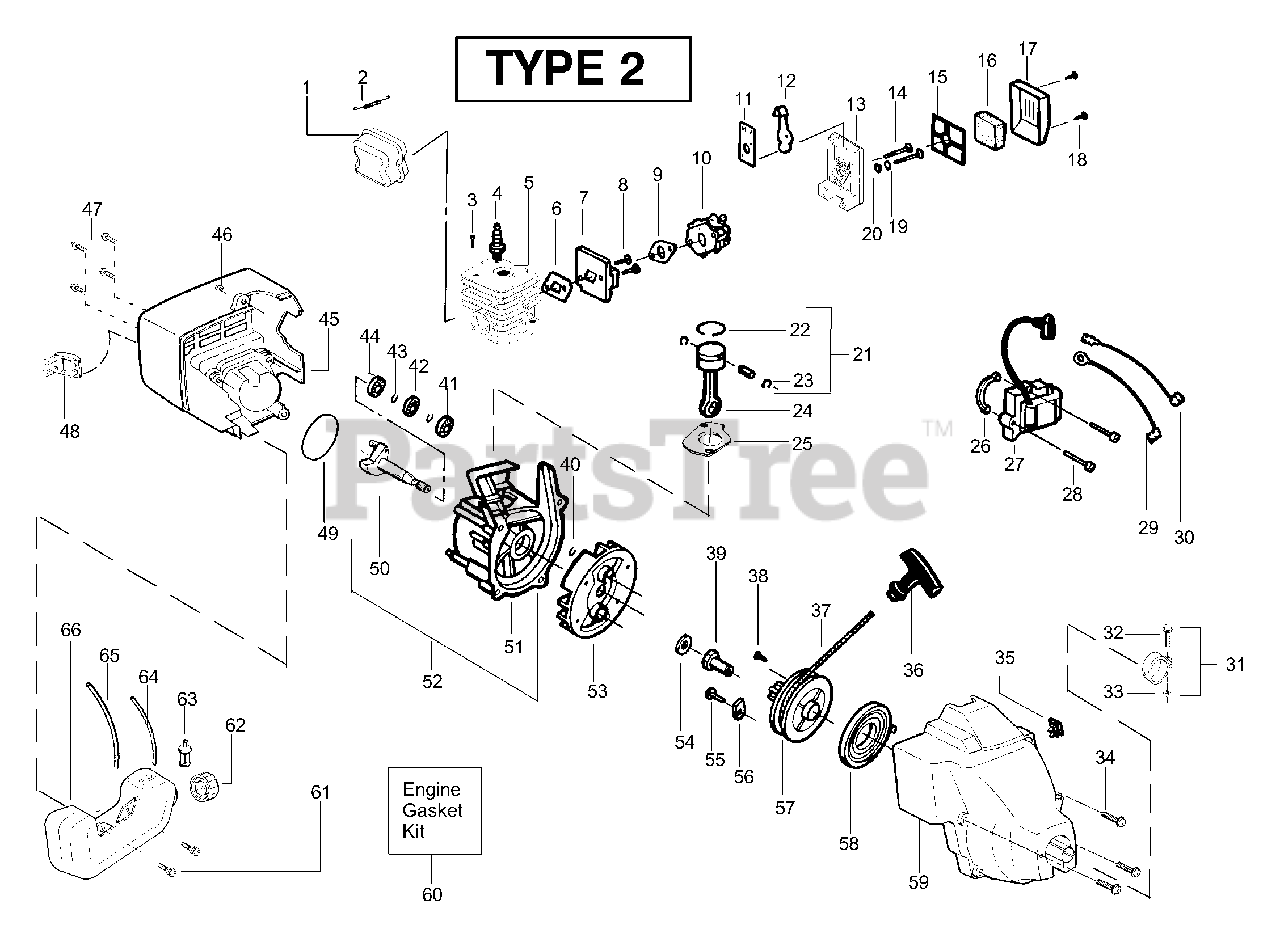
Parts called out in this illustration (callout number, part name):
1	Kit - Muffler
2	Spring-Muffler
3	Screw-Cylinder
4	Spark Plug (RCJ-6Y)
5	Kit - Cylinder
6	Gasket-Cyl/Carb.(kit)
7	Adaptor-Carb.
9	Gasket-Carb.(kit)
10	Kit - Carburetor Ass'y
11	Plate-Choke Mounting
12	Shutter-Choke
15	Plate - Filter Support
16	Foam-Air Filter
17	Cover-Air Filter
19	Spacer-Choke
21	Kit - Piston
22	Ring-Piston
23	Retainer-Piston Pin
24	Assy-Connecting Rod
25	Gasket-Cylinder (kit)
26	Spacer-Module
27	Module-Ignition
29	Assy-Ground Wire
30	Assy-Leadwire
31	Assy-Nose Cone Clamp
32	Screw-Nose Cone
33	Nut-Nose Cone
34	Screw
35	Kit-Momentary Switch
36	Handle-Starter
37	Kit - Rope
39	Coupling-Drive
40	Retain. Ring-C'shaft
41	Bearing-Outer
42	Seal-C'case
43	Retainer Ring-C'case
44	Bearing-Inner
45	Kit-Fan Hsg./Shroud
47	Screw
48	Guard-Muffler
49	O-Ring-C'case (kit)
50	Assy-Crankshaft
51	Assy-Crankcase
52	Assy-C'case & C'shaft
53	Assy-Flywheel
54	Washer-Flat
56	Retainer
57	Kit-Starter Pulley
58	Spring-Starter
59	Kit-Fan Hsg./Shroud
60	Kit-Engine Gasket
61	Retainer-Fuel Tank
62	Assy-Fuel Cap w/ret.
63	Assy-Fuel Pickup
64	Kit-Fuel Line (Small)
65	Kit-Fuel Line (Large)
66	Assy-Fuel Tank
